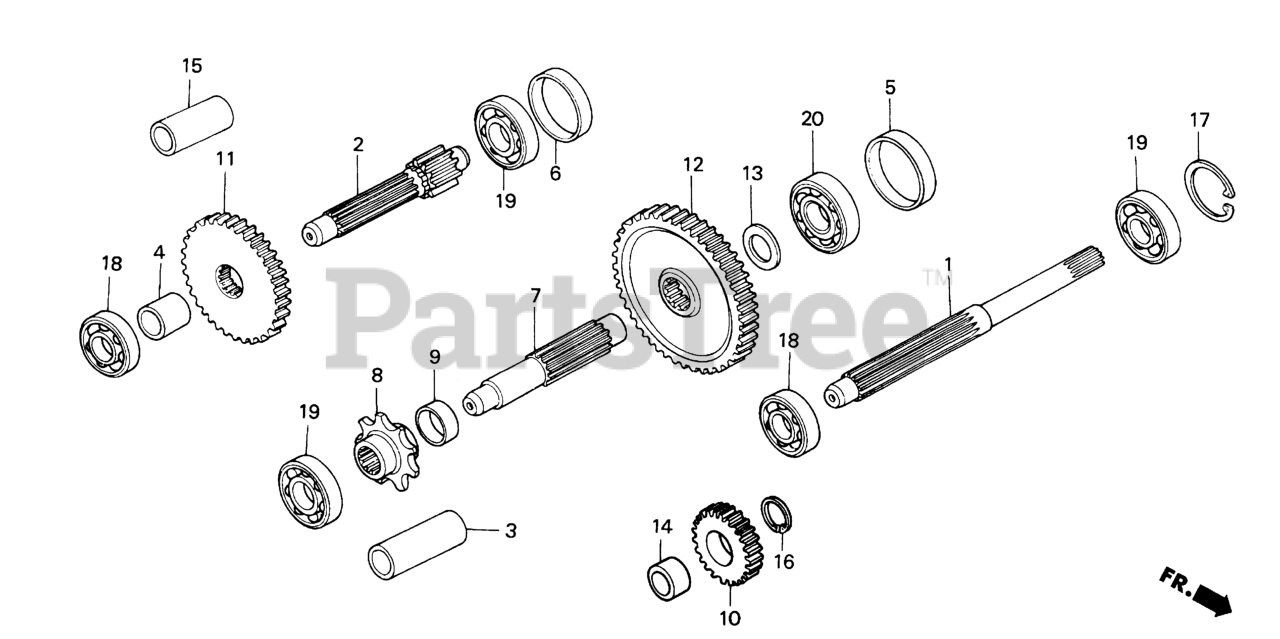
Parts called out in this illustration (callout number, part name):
1	SHAFT, INPUT
2	COUNTERSHAFT (13T)
3	COLLAR (22) (2X30)
4	COLLAR A, COUNTERSHAFT
5	COLLAR A, DISTANCE
6	COLLAR B, DISTANCE
7	SHAFT, FINAL
8	SPROCKET, DRIVE (9T)
9	COLLAR, FINAL SHAFT
10	GEAR, DRIVE
11	GEAR, COUNTERSHAFT SECOND (45T)
12	GEAR, FINAL (58T)
13	WASHER (17MM)
14	COLLAR, INPUT (B)
15	COLLAR, COUNTER (C)
16	CIRCLIP (OUTER) (18MM)
17	CIRCLIP (INNER) (35MM)
18	BEARING, RADIAL BALL (6002)
19	BEARING, RADIAL BALL (6202)
20	BEARING, RADIAL BALL (6203)
